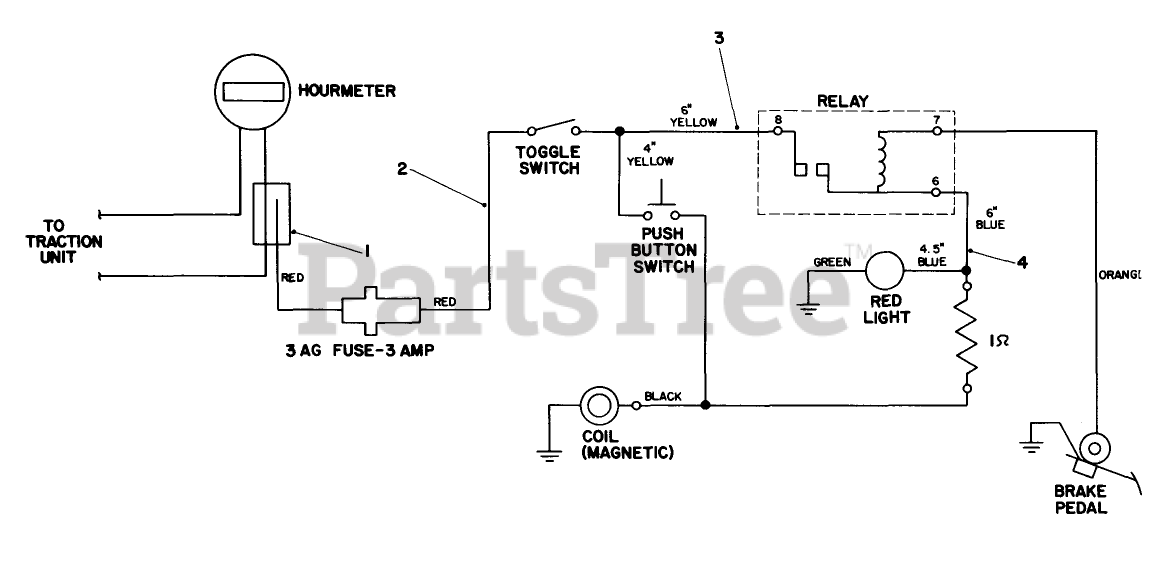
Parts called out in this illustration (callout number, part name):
1	TAP CONNECTOR
2	Wire Harness
3	WIRE ASM
4	WIRE ASM
